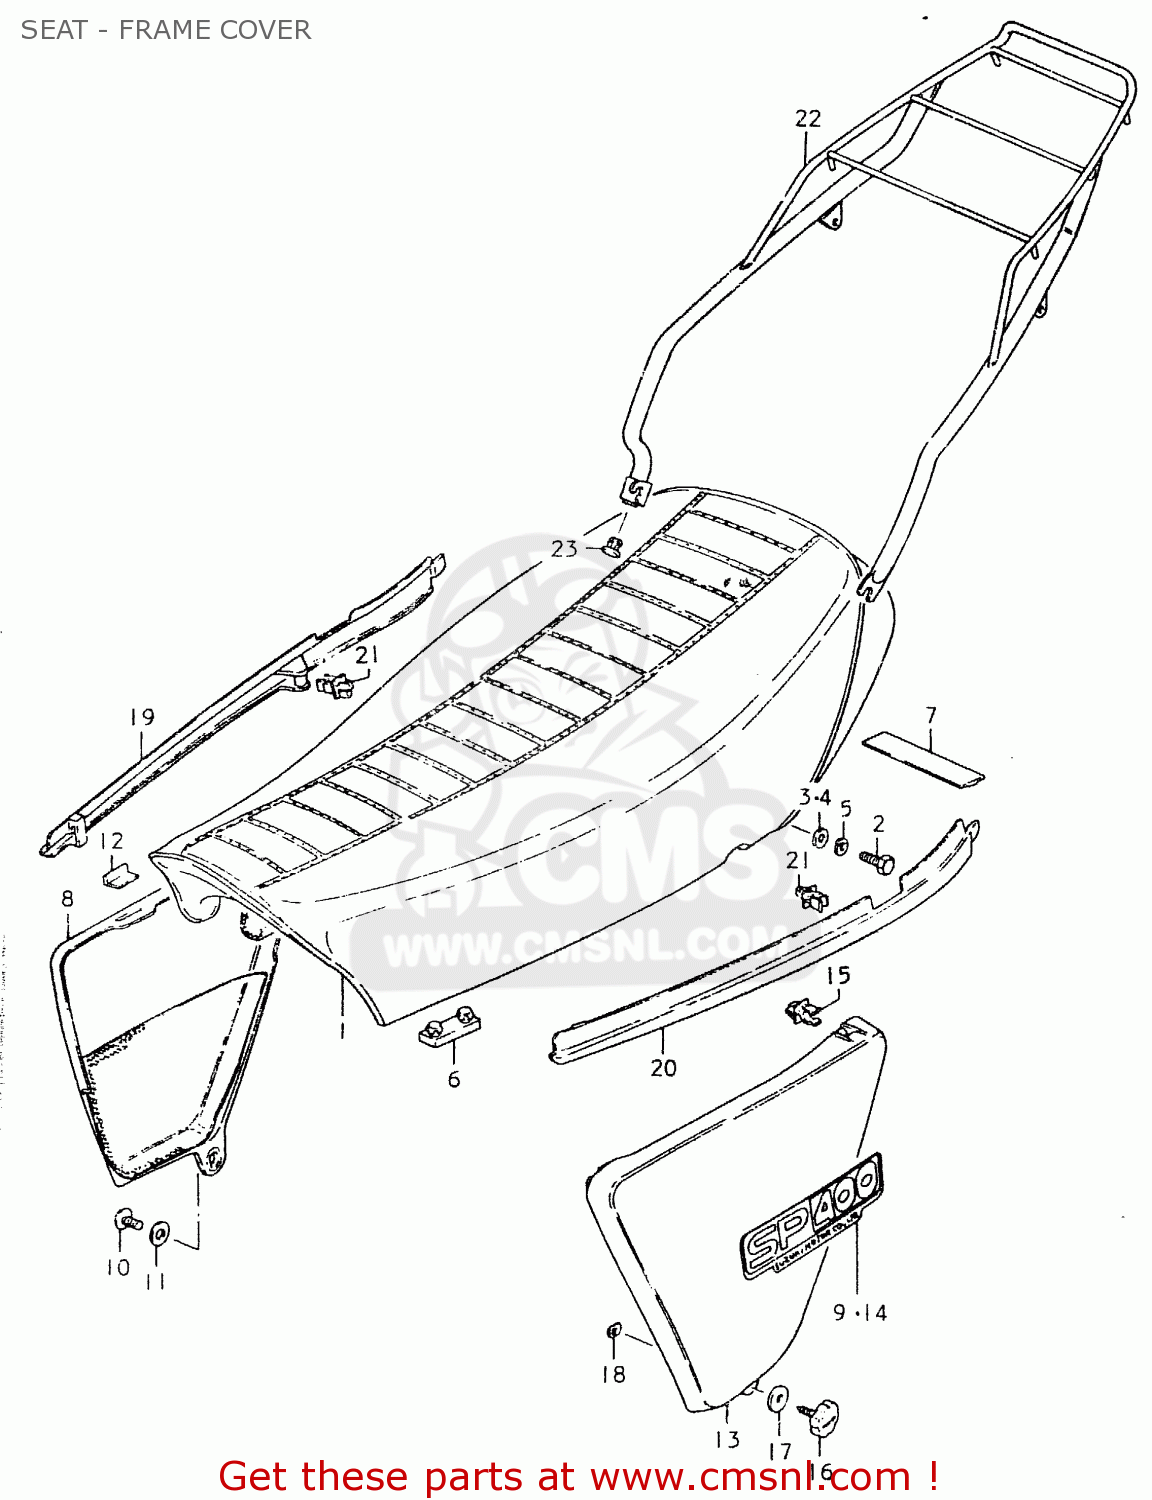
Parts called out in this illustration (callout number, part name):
1	SEAT
2	BOLT
3	WASHER
4	WASHER (8.2X20X1.6)
5	LOCK WASHER
6	CUSHION
7	CUSHION,FRAME
8	COVER,FRAME,R(BLACK)
9	EMBLEM
10	SCREW
11	WASHER
12	CUSHION,FRAME COVER
13	COVER,FRAME,LEFT
14	EMBLEM
15	CLAMP
16	KNOB,FRAME COVER,R
17	WASHER
18	NUT
19	COVER,FRAME
20	COVER, SEAT LOWER LH
21	CLAMP
22	CARRIER
23	CAP(OD:17)
